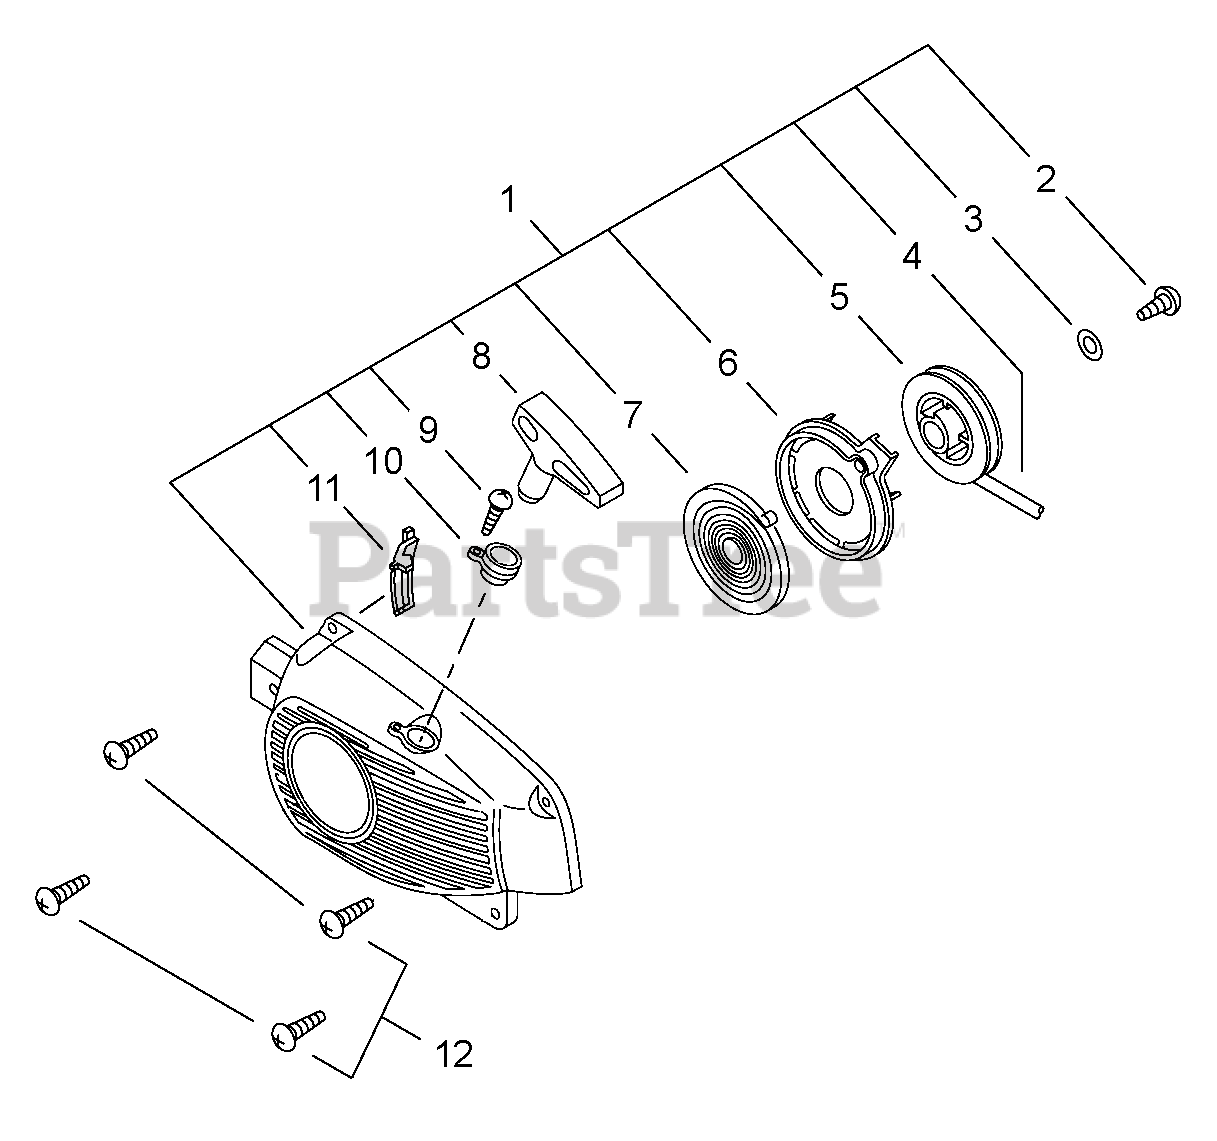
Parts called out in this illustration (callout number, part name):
1	STARTER ASSY
2	SCREW - 4X14
4	ROPE, STARTER - 3X850
5	REEL, ROPE
6	PLATE, STARTER
7	SPRING, REWIND
8	GRIP, STARTER
9	SCREW - 3X14
10	GUIDE, ROPE
12	SCREW - 4X16
